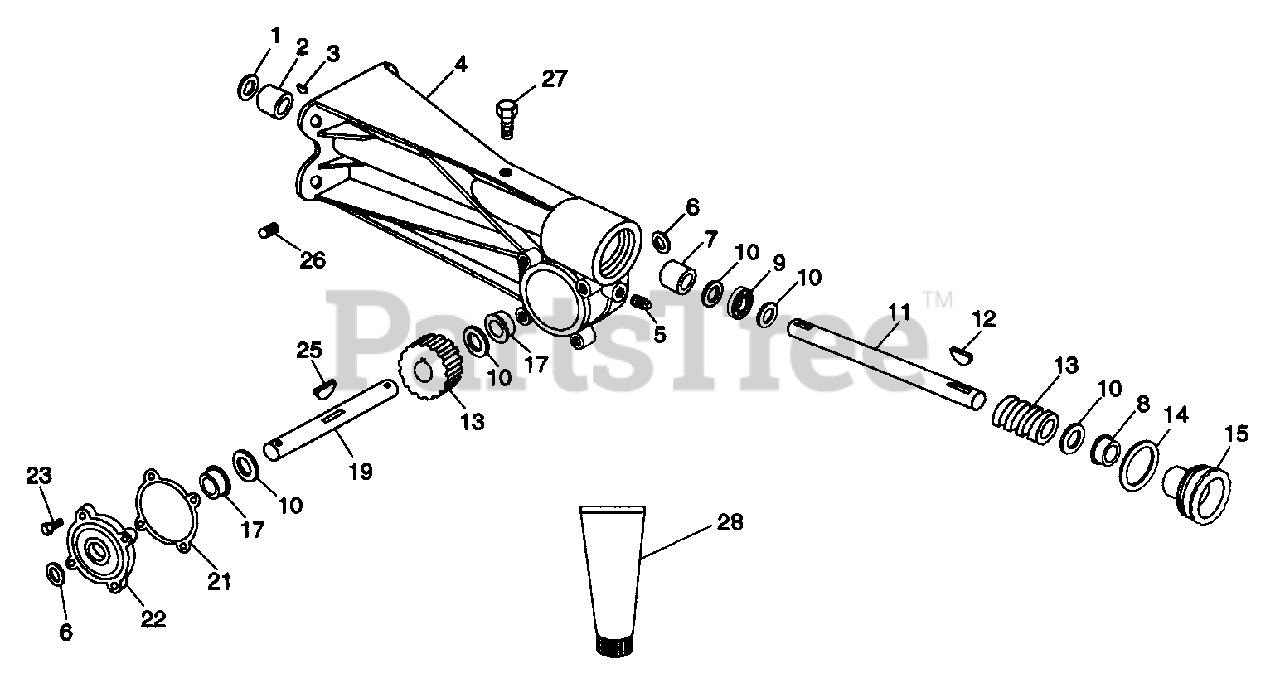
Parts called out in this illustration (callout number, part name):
1	SEAL .750X1.000X.125
2	BSHG-SLV .750X1.000X1.000
3	KEY-WDRF .188X.875X.375 SAE11
4	GEARCASE - ALUMINUM
5	PIPE PLUG
6	SEAL .750X1.980X.375
7	BSHG-SLV .750X1.000X.750
8	BSHG-FLG .750X1.000X.750X1.132
9	BRG-N THRST .754X1.24X.078
10	WSHR-HDND-THRST .755X1.40X.062
11	WORM SHAFT
12	KEY-FTHR .188X1.38X.188
13	WORM AND WORM GEAR SERVICE
15	ADJUSTMENT PLUG
17	BSHG-FLG .750X1.250X.750X1.375
19	TINE SHAFT
23	SCR-TAP .312-18X1.0 HWH PL TR
24	WSHR-LK .312X.097 PL HVY
25	KEY-WDRF .188X.625X.25 SAE 61
26	BREATHER
27	SCR-TAP .375-16X .50 HWH PL TR
28	ARIENS 16 OZ.BOTTLE OF L2 LUBE
